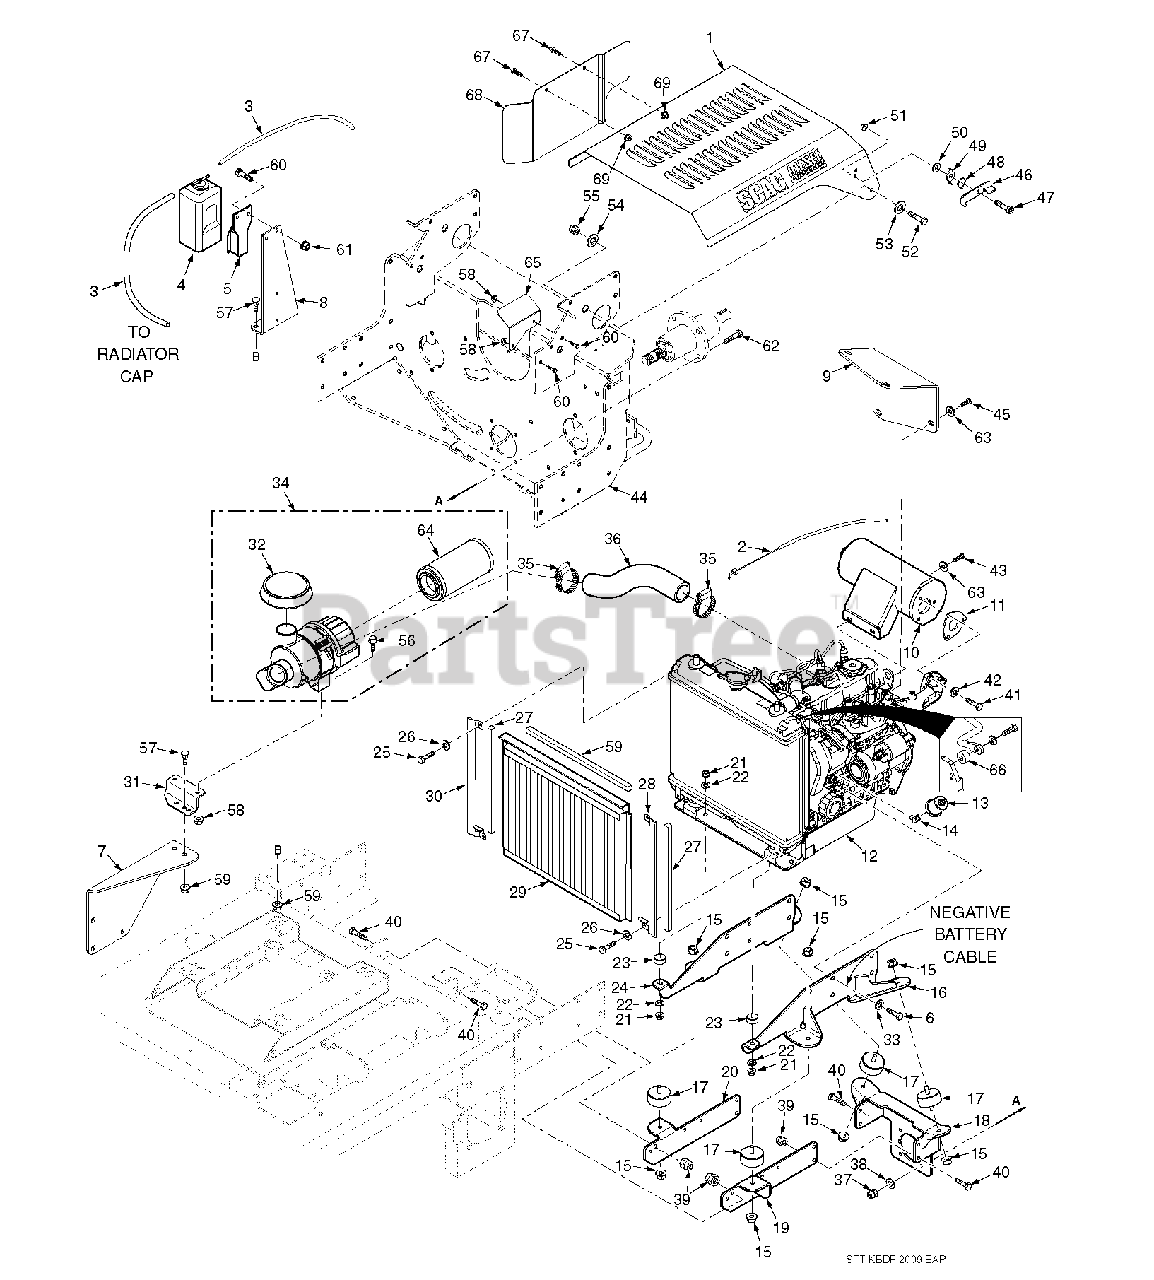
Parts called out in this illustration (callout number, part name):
1	Hood Assembly
2	Throttle Cable
3	Hose, Over Spill Bottle
4	Over Spill Bottle
5	Mounting Bracket, Over-Spill Bottle
6	Bolt, Metric Hex Hd. M10-1.25 x 25mm
7	Bracket, Kubota Air Cleaner
8	Bracket, Kubota Coolant Overflow Bottle
9	Bracket, Kubota Coil
10	Muffler, Kubota
11	Gasket, Muffler
12	Engine, Kubota
13	Oil Pressure Sender
14	Elbow, 45 Deg.
15	Nut, Serr. Flng. 5/16-18
16	Mounting Bracket Weldment LH
17	ISO Mount
18	Plate, Rear Engine Mount
19	Plate, Engine Mount LH
20	Plate, Engine Mount RH
21	Nut, Metric Hex M8-1.25mm
22	Lockwasher, 5/16" Spring
23	Rubber ISO Mount, Radiator
24	Mounting Bracket Weldment RH
25	Capscrew, Metric M6-1.0 x 16mm
26	Lockwasher, 1/4" Spring
27	Foam, Radiator Screen
28	Debris Screen Track LH
29	Debris Screen Assembly
30	Debris Screen Track RH
31	Bracket, Air Cleaner Mount
32	Rain Cap
33	Lockwasher, 7/16" Spring
34	Air Filter Assembly
35	Clamp, 2-1/4" Max. Dia.
36	Hose, Air Intake
37	Nut, Elastic Stop 5/16-18 Grd. 8
38	Lockwasher, 5/16" Spring
39	Nut, Elastic Stop 3/8-16
40	Bolt, Hex Hd. 3/8-16 x 1"
41	Bolt, Metric Hex Hd. M8-1.25 x 30mm
42	Lockwasher, 5/16" Spring
43	Bolt, Metric Hex Hd. M8-1.25 x 25mm
44	Pump Mounting Plate Weldment
45	Bolt, Metric Hex Hd. M8-1.25 x 25mm
46	Latch, Hood
47	Bolt, Shoulder 5/16-18 x 1/2"
48	Spring, Hood Latch
49	Lock, Hood Latch
50	Flatwasher, 3/8 (.391 x .938 x .105")
51	Nut, Center Lock 5/16-18
52	Bolt, Hex Hd. 3/8-16 x 1-3/4"
53	Flatwasher, 3/8 (.391 x .938 x .105")
54	Flatwasher, 3/8 (.406 x 1.50 x 7 Ga.)
55	Nut, Elastic Stop 3/8-16
56	Bolt, Hex Hd. Serr. Flng. 5/16-18 x 3/4"
57	Bolt, Carriage 5/16-18 x 3/4"
58	Nut, Serr. Flng. 5/16-18
59	Foam, Radiator Screen Upper
60	Bolt, Hex Hd. Serr. Flng. 5/16-18 x 3/4"
61	Nut, Serr. Flng. 5/16-18
62	Bolt, Hex Hd. 5/16-18 x 1-3/4" Grd. 8
63	Flatwasher, SAE 5/16 (.344 x .688 x .065")
64	Air Filter, Outer
65	Shield, Battery
66	Spacer, Radiator
67	Bolt, Serr. Flng 1/4-20 x 3/4"
68	Heatshield, Air Cleaner STT-DF
69	Nut, Serr. Flng 1/4-20
